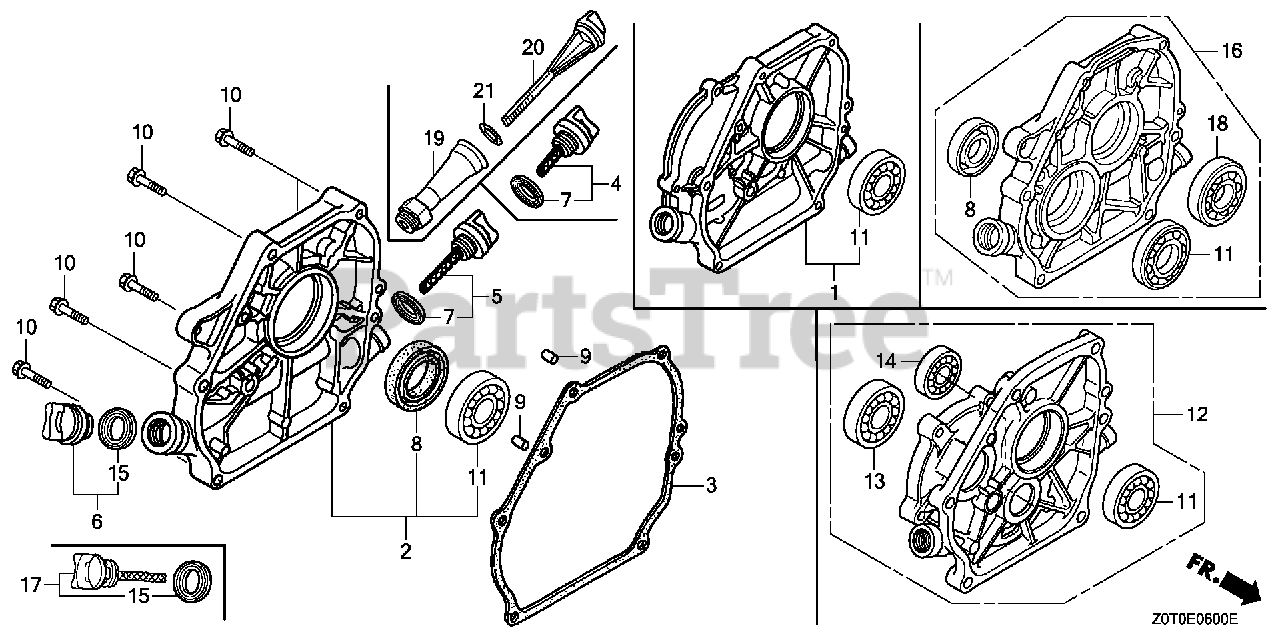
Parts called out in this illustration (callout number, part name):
2	COVER ASSY., CRANKCASE
3	GASKET, CASE COVER (NON-ASBESTOS)
5	CAP ASSY., OIL FILLER (GAUGE)(GRAY)
6	CAP ASSY., OIL FILLER (BLACK)
7	GASKET, OIL FILLER CAP
8	OIL SEAL (25X41X6) (NOK)
9	PIN, DOWEL (8X14)
10	BOLT, FLANGE (8X32)
11	BEARING, RADIAL BALL (6205)
15	GASKET, OIL FILLER CAP
